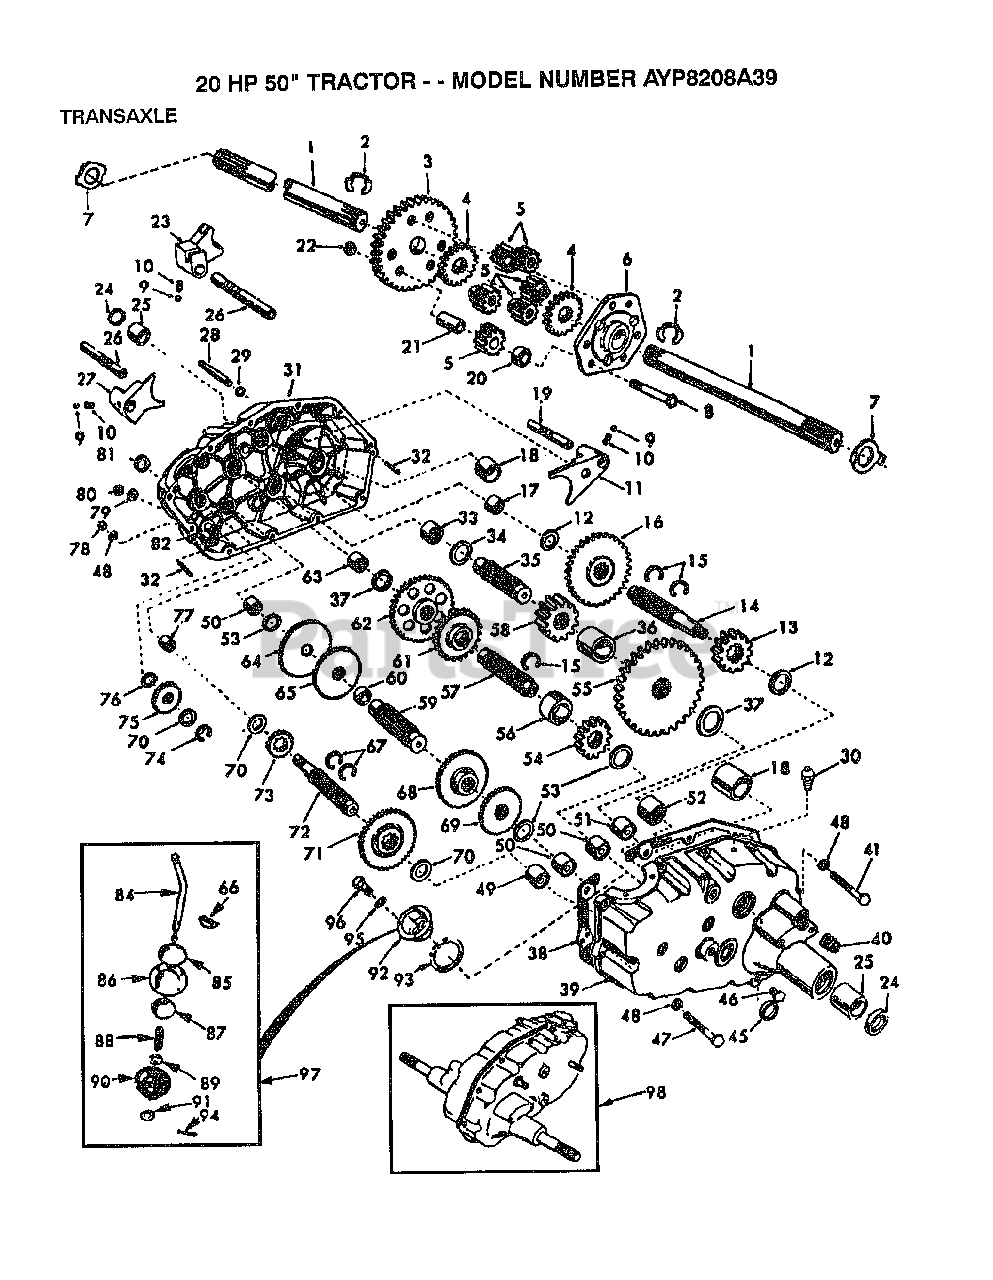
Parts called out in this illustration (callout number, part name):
1	SHAFT.AXLE.T
2	KLIP RING
3	FINAL GEAR T
4	DIFF GEAR T
5	DIFF PINION T
6	DIFF CARRIER T
8	BOLT
11	SHIFT FORK T
12	WASHER .T
13	RED PINION T
14	GEAR SHAFT T
15	SNAP RING T
16	GEAR T
17	"T, BEARING"
18	BEARING
19	SHAFT
20	SPACER T
21	PINION RS
22	GRIPCO NUT
23	FORK T
24	OIL SEAL STD
25	BRNG. T
27	SHIFT FORK T
28	SHIFT SHAFT
29	SEAL T
30	VALVE M
32	PIN T
33	NEEDLE BRNG T
34	RACE T
35	GEAR SHAFT T
37	RACE T
38	GASKET
40	PLUG PIPE
41	BOLT
45	SEAL T
47	HEX BOLT
49	"TI, BEARING"
50	NEEDLE BRNG T
51	NEEDLE BRNG T
52	"STD, BEARING"
53	BRNG RACE
54	RED PINION T
55	RED GEAR T
56	PINION SPACER T
57	GEAR SHAFT T
58	FINAL PINION T
59	GEAR SHAFT T
60	SPACER T
61	RED PINION T
62	RED GEAR T
63	RACE T
64	LOW SPEED GEA T
65	REVERSE GEAR T
66	KEY T
67	RING STD
68	INTERMED GEAR T
70	"T, BEARING"
71	CLUSTER GEAR T
72	INPUT SHAFT T
73	LO SPEED PINION T
75	IDLER GEAR T
76	WASHER T
77	BRNG T
78	NUT.HEX.5/16-18
79	WASHER T
80	NUT
81	SEAL STD
84	GEAR SHIFT LVR T
85	CAP T
86	COVER AND PIN T
87	GUIDE BALL T
88	SPRING TI
89	WASHER
90	SEAL T
91	WASHER
92	GEAR SHIFT GA T
93	GASKET T
94	COTTER PIN
95	LOCKWASHER
96	BOLT
97	GEAR SHFT LVR T
